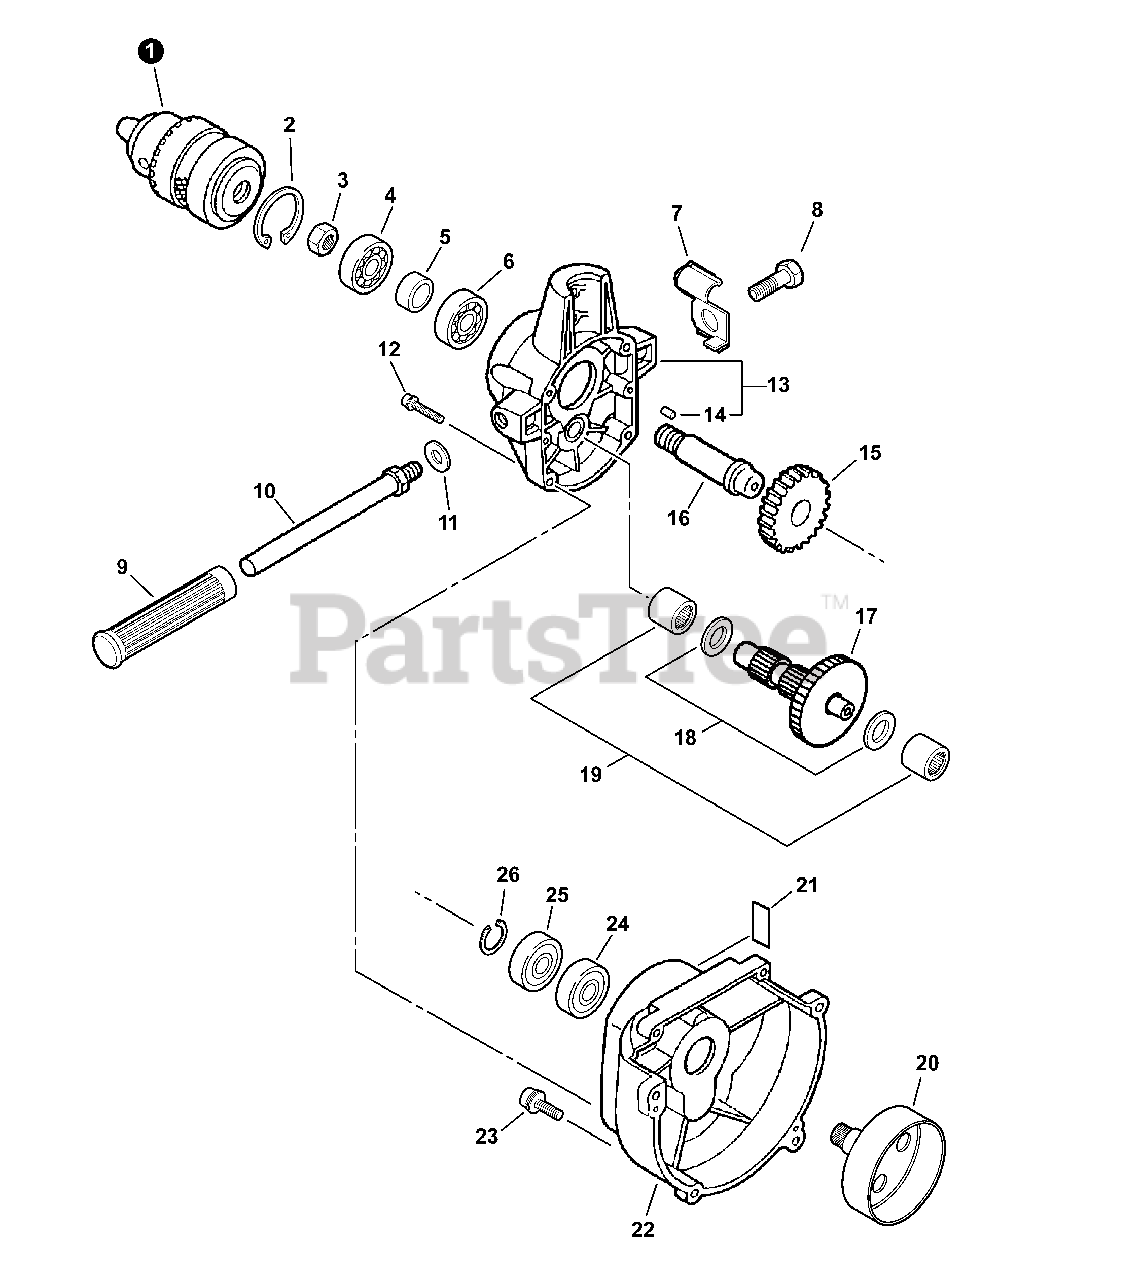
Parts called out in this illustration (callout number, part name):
2	RING, RETAINING - 32
3	NUT - 12
4	BEARING, BALL - 6002
6	BEARING, BALL - 6002
7	SPRING, FLAT
8	BOLT - 10×15
9	GRIP, HANDLE
10	HANDLE - FRONT
11	WASHER - 10
12	SCREW - 5×25
13	GEAR CASE ASSY
14	PIN - LOCATING
15	GEAR - SPUR
16	GEAR - SHAFT
17	GEAR - SHAFT
19	BEARING, NEEDLE
20	DRUM, CLUTCH
21	LABEL - HOT SURFACE
22	CASE, FAN
23	SCREW - 4×16
24	BEARING, BALL - 6001
25	BEARING, BALL - 6001
26	RING, RETAINING - 12
